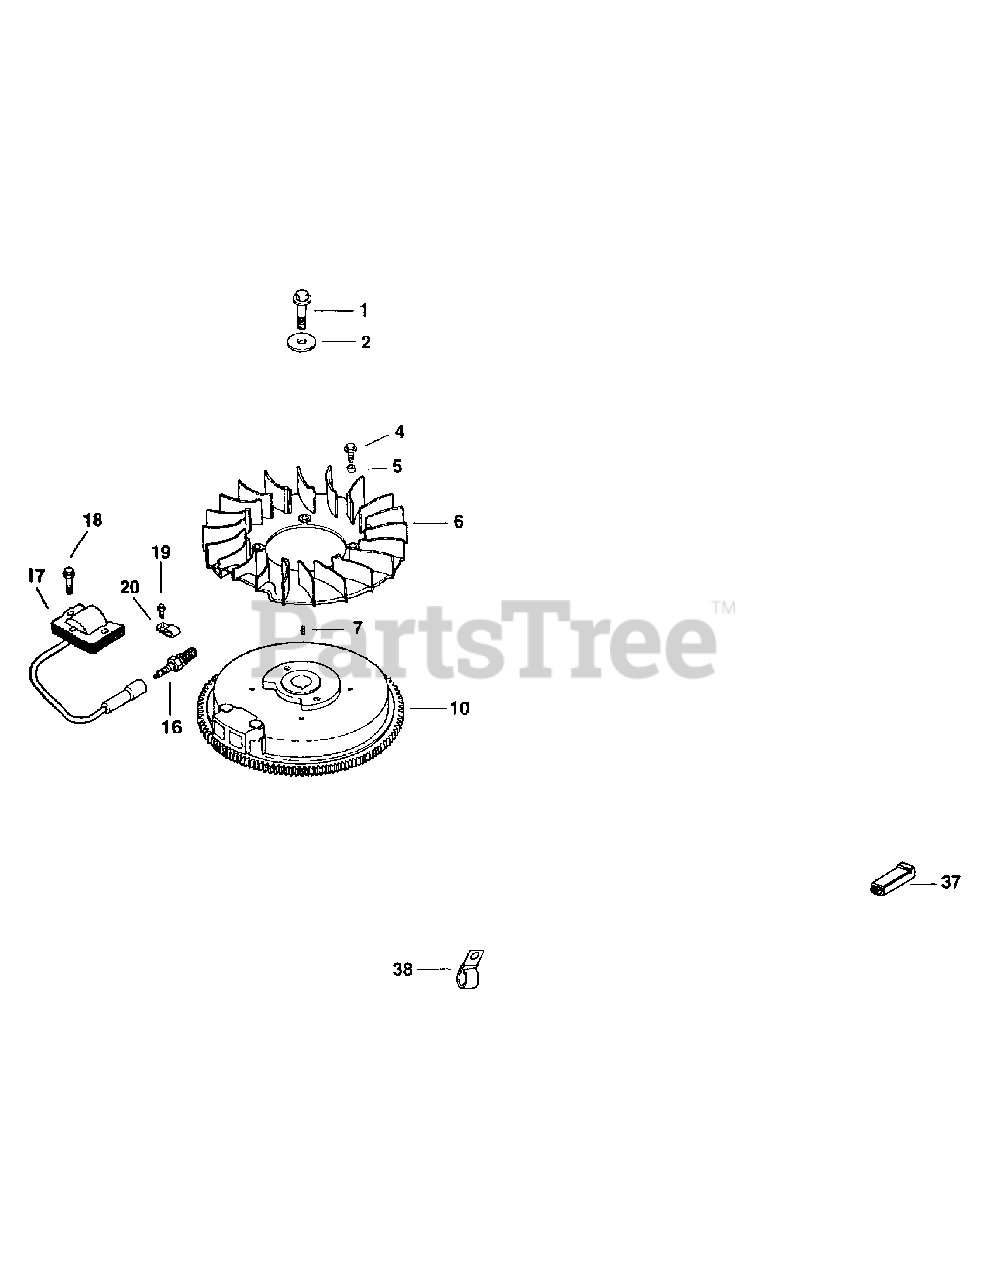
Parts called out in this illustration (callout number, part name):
1	Screw, Hex Flange
2	Washer, Plain 3/8"
4	Screw, Hex Flange
5	Spacer, Fan
6	Fan, Flywheel
10	Flywheel
13	Screw, Hex Flange
16	Spark Plug
17	Module, Ignition
18	Screw, Hex Flange
19	Screw, Hex Flange
20	Clip, Kill Lead
22	Cup And Screen
37	Connector
